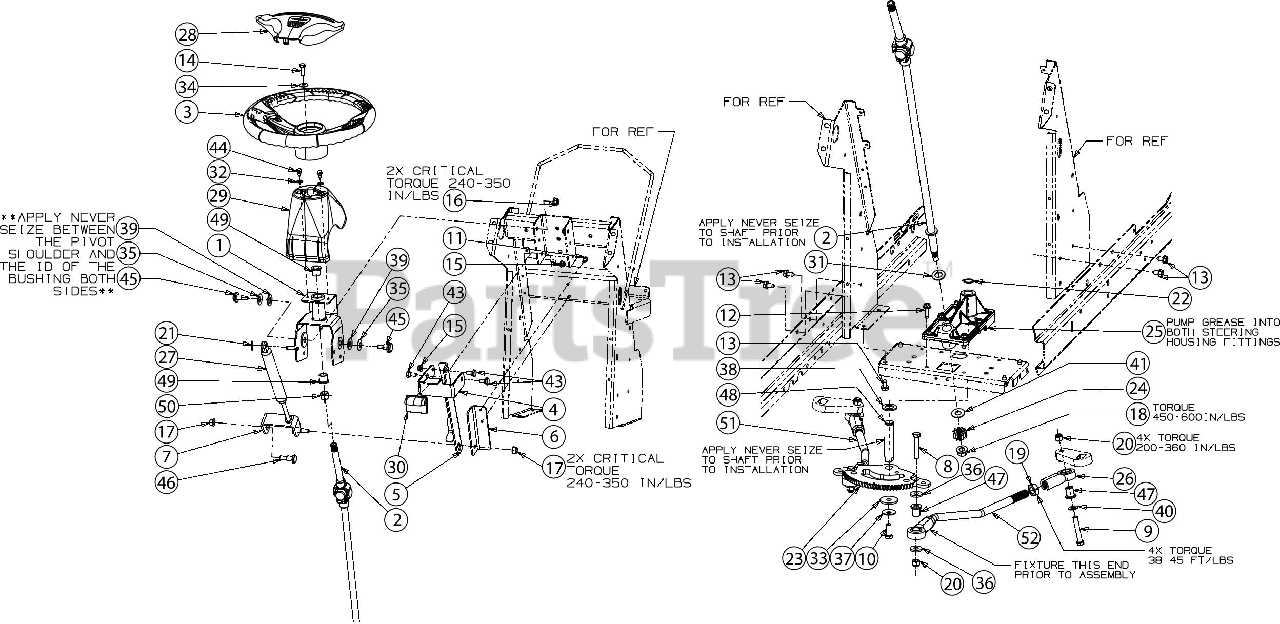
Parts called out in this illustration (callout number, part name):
1	UPPER STEERING BRACKET ASSEMBLY
2	STEERING SHAFT ASSEMBLY
3	STEERING WHEEL
4	TILT LEVER BRACKET
5	TILT ENGAGE BRACKET
6	TILT STEERING BRACKET
7	DAMPER CYLINDER PIVOT BRACKET
8	HEX SCREW 3/8-24 X2.00
9	HEX SCREW 3/8-24 x 2.25 GR5
10	SCREW 3/8-24 x 1.00 GR5
11	SCREW 1/4-20 X.500
12	SCREW 5/16-18 x 1.00
13	SCREW 5/16-18 x .625
14	SCREW 5/16-18 x 1.00 GR5
15	FLANGE LOCK NUT 5/16-18
17	HEX LOCK NUT
18	FLANGE LOCK NUT
19	HEX JAM NUT 5/8-18
20	INSERT NUT
21	COTTER PIN 3/32
22	SNAP RING
23	STEERING GEAR SEGMENT
24	STEERING PINION GEAR
25	STEERING HOUSING ASSEMBLY
26	BALL JOINT ROD END
27	DAMPER CYLINDER
28	STEERING WHEEL COVER
29	STEERING COLUMN
30	TILT WHEEL LEVER
31	FLAT WASHER .635 ID x 1.12 OD x .090
32	FLAT WASHER .344 ID x .62 OD x .033
33	FLAT WASHER .390x1.500x.134
34	BELL WASHER .337 X.867 x .057
35	BELL WASHER
36	FLAT WASHER .385 x 1.00 x .135
37	BELL WASHER .390x1.130x.062
38	SHIM WASHER .76X1.25X.10
39	FLAT WASHER
40	FLAT WASHER
41	FLAT WASHER
43	SHOULDER SCREW .437
44	SHOULDER SCREW 1/4-20X.50 19"PSH
45	BOLT-SHLDR .49 DIA x .50
46	SHOULDER BOLT .50 DIA x .66
47	SHOULDER SPACER
48	STEERING SHAFT SEGMENT
49	FLANGE BEARING
50	SLEEVE BEARING
51	STEERING DRAG LINK (LH)
52	STEERING DRAG LINK (RH)
